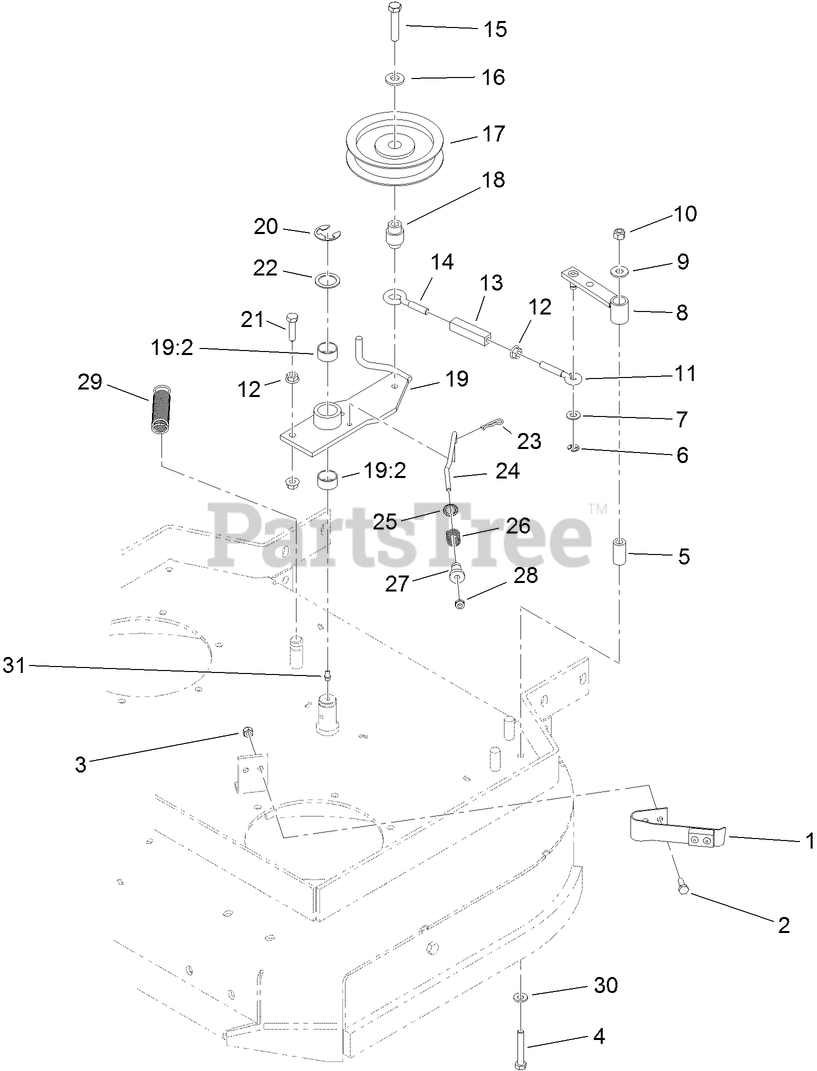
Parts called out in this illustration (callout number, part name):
1	PAD AND SPRING ASM
2	SCREW-HH
3	NUT-LOCK, NI
4	SCREW-HH
5	TUBE-PIVOT
6	RING-RETAINING, EXT
7	WASHER-PLAIN
8	ARM-ASSIST
9	WASHER-FLAT
10	NUT-LOCK, NI
11	EYEBOLT-THREAD, RH
12	NUT-HF
13	BODY-TURNBUCKLE
14	EYEBOLT-THREAD, LH
15	SCREW-HH
16	WASHER-BELLEVILLE
17	PULLEY-IDLER
18	BUSHING-ENGAGEMENT
19	Idler Arm ASM
19:2	SLEEVE-BEARING
20	RING-RETAINING, EXT
21	SCREW-HH, SPECIAL
22	WASHER-SPINDLE
23	PIN-COTTER
24	ROD-BRAKE
25	RING-PUSH ON
26	SPRING-COMPRESSION
27	SPACER-FLANGED
28	NUT-LOCK, NI
29	SPRING-EXTENSION
30	WASHER-SPRING
31	FITTING-GREASE, 90 DEG
